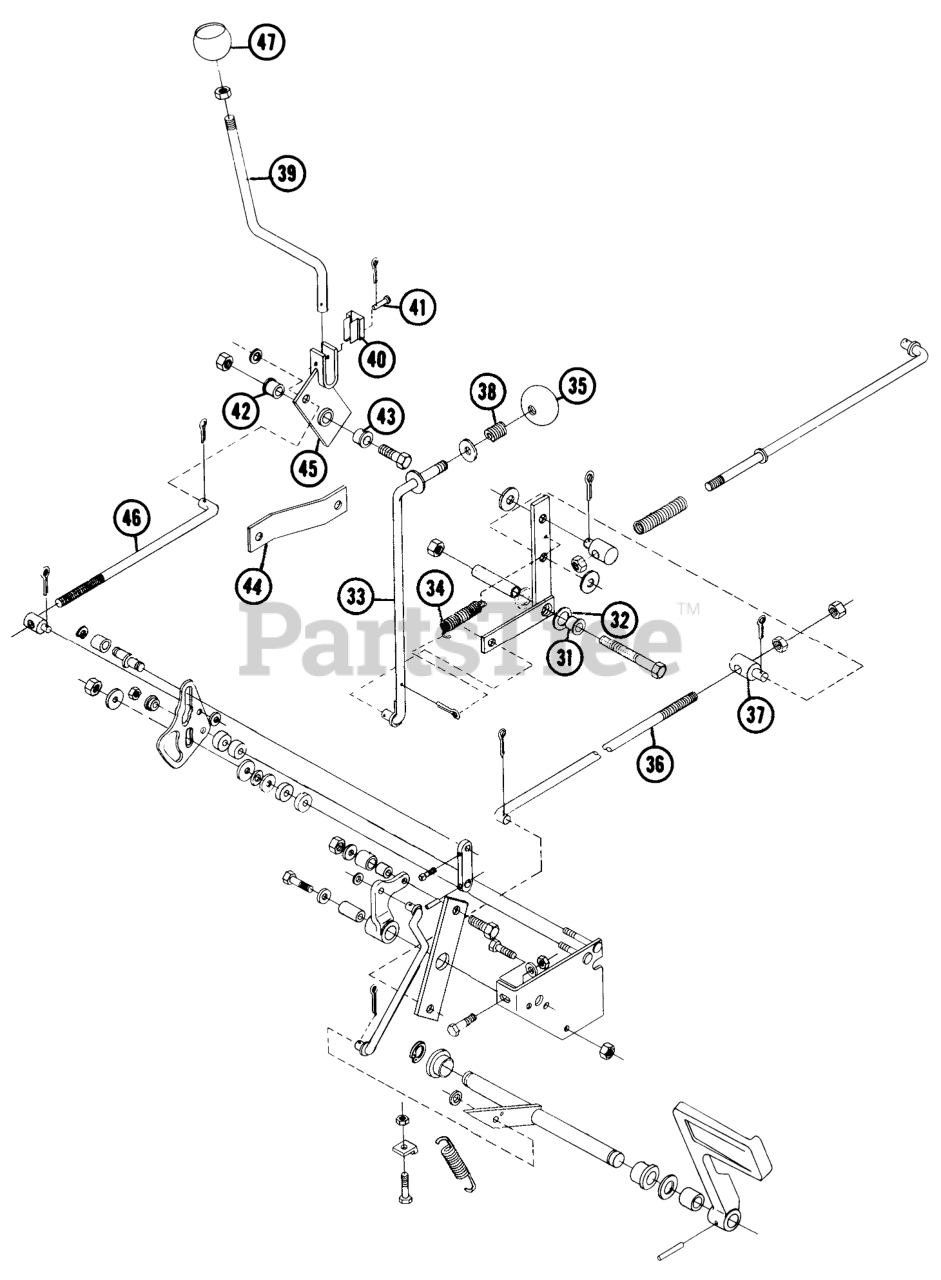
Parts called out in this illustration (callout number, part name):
1	Assy-Plate
1	HHCS
1	Nut
1	WASHER 5/16 SAE
1	Screw
2	Lever-Neutral Return
3	BEARING-CAM RETURN
4	SPACER
4	BOLT
4	Nut
4	Washer
6	Spacer
6	Bolt
6	NUT
6	WASHER
7	ROD ASSY
7	Washer
7	Cotter Pin
8	Arm-Speed Control
8	PIN-ROLL 1/4 X 1 1/4
9	ECCENTRIC-CAM FOLLOW
10	Spacer
10	E RING
11	SET SCREW
12	Cam-Speed Control
13	CAM-SPACER
13	Nut
14	Spacer
15	SPACER
16	WASHER-SPRING DISC
17	FRICTION WASHER
17	Nut Conlok 3/8-16
18	Washer
19	Assy-Shaft
20	BEARING
20	E-RING
21	Spacer
22	WASHER
23	Brake Pedal
23	PIN-ROLL, SPIROL
24	SPRING-EXTENSION
25	CLIP - SPRING
25	Bolt
25	NUT
26	Assy-Rod
27	Spring
28	TRUNNION-LIFT
28	NUT
29	Assy-Arm Brake
29	HHCS
30	Washer
30	Spacer
31	FLANGED BUSHING
32	NUT
32	Washer
33	Assy-Brake Rod
33	Washer-Nylon
34	SPRING
35	SHIFT KNOB
36	Rod
36	Cotter Pin
37	TRUNNION-LIFT
37	Nut
38	SPRING-COMPRESSION
39	HANDLE
40	Spring
41	Cotter Pin
41	Clevis Pin
42	CAM-SPACER
43	FLANGED BUSHING
44	Brace
45	ASSY-PIVOT
45	Bolt
45	NUT
45	Washer
45	Cotter Pin
46	Washer
46	Cotter Pin
47	Jam Nut
